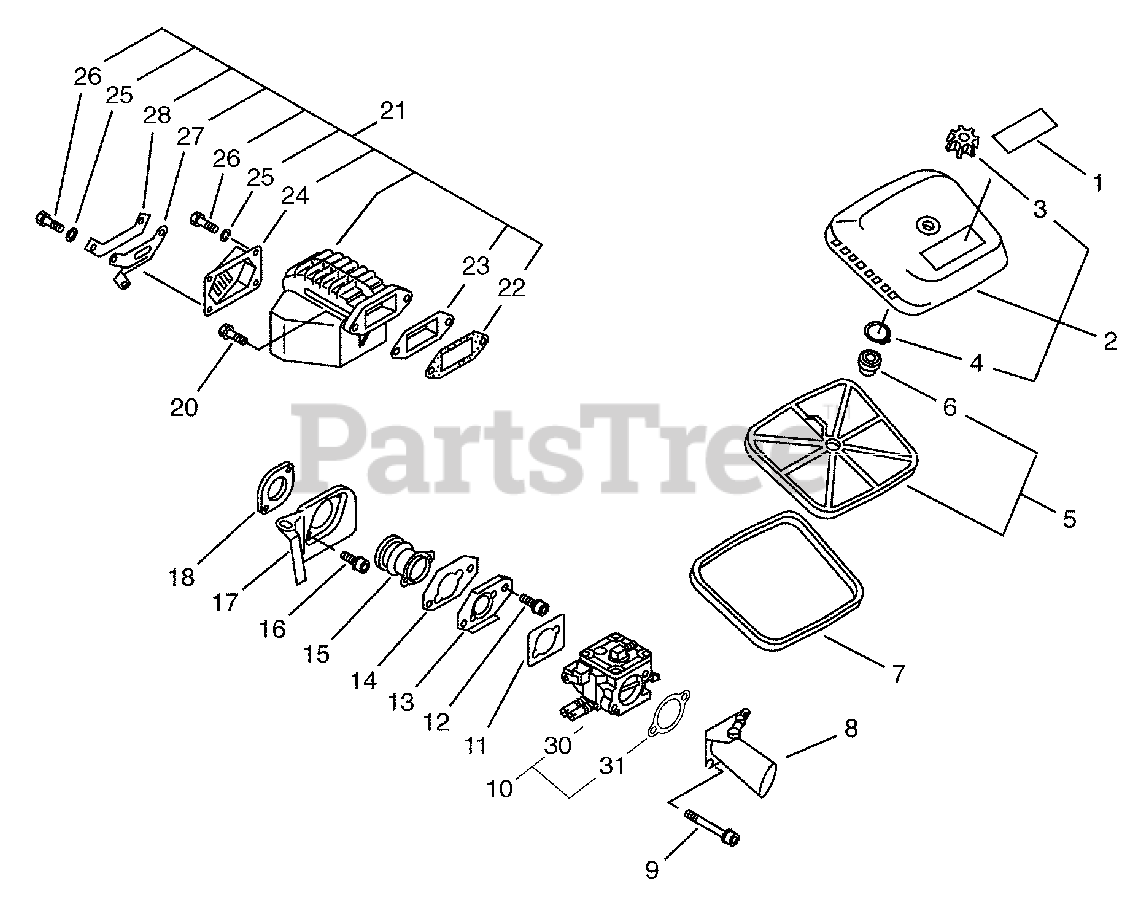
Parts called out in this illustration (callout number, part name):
1	LABEL, MODEL
2	COVER ASSY, AIR FILTER
5	FILTER, AIR
6	GASKET, AIR FILTER
8	ADAPTOR, INTAKE
9	BOLT 5×50
10	CARBURETOR
12	BOLT 5×14
13	ADAPTOR, CARBURETOR
14	SEAL, DUST
15	BELLOWS, INTAKE
16	BOLT 5×20
20	BOLT 6×25
21	MUFFLER ASSY
22	GASKET, EXHAUST
23	SILENCER
24	GUIDE, EXHAUST
25	WASHER 5.2×8×0.8T
26	SCREW - 5×18
28	WASHER
30	CARBURETOR
31	GASKET, INTAKE
